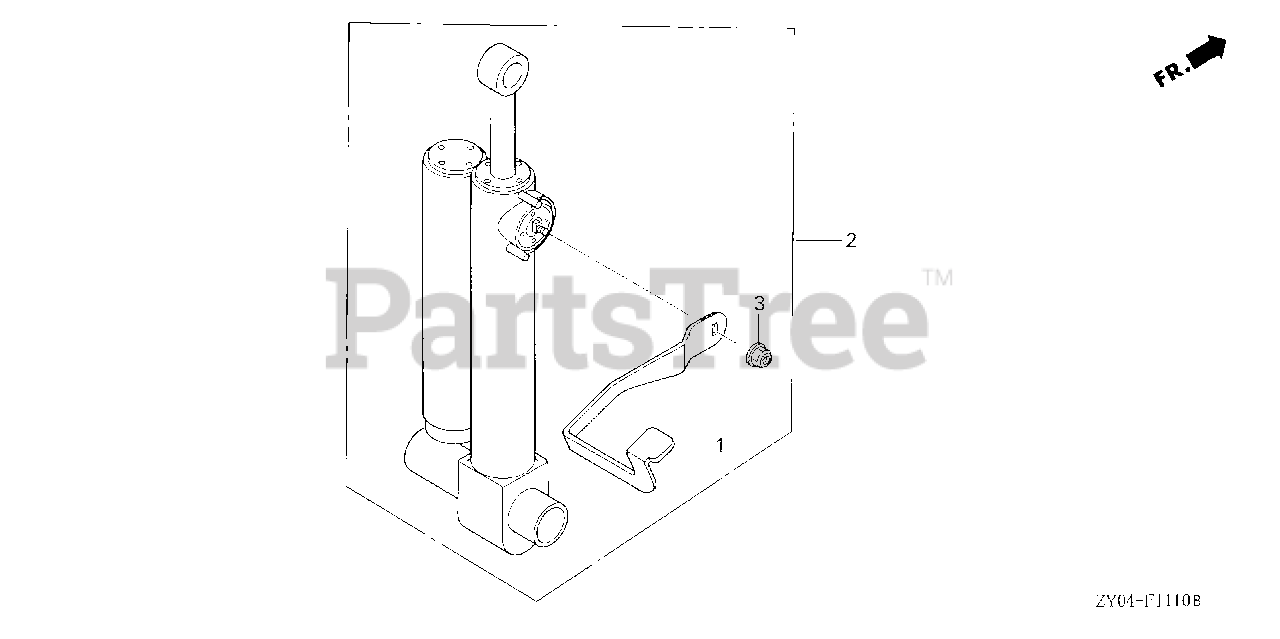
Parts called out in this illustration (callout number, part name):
1	LEVER, TILT
2	SHOCK ABSORBER ASSY., GAS
3	NUT, SELF-LOCK (6MM)
